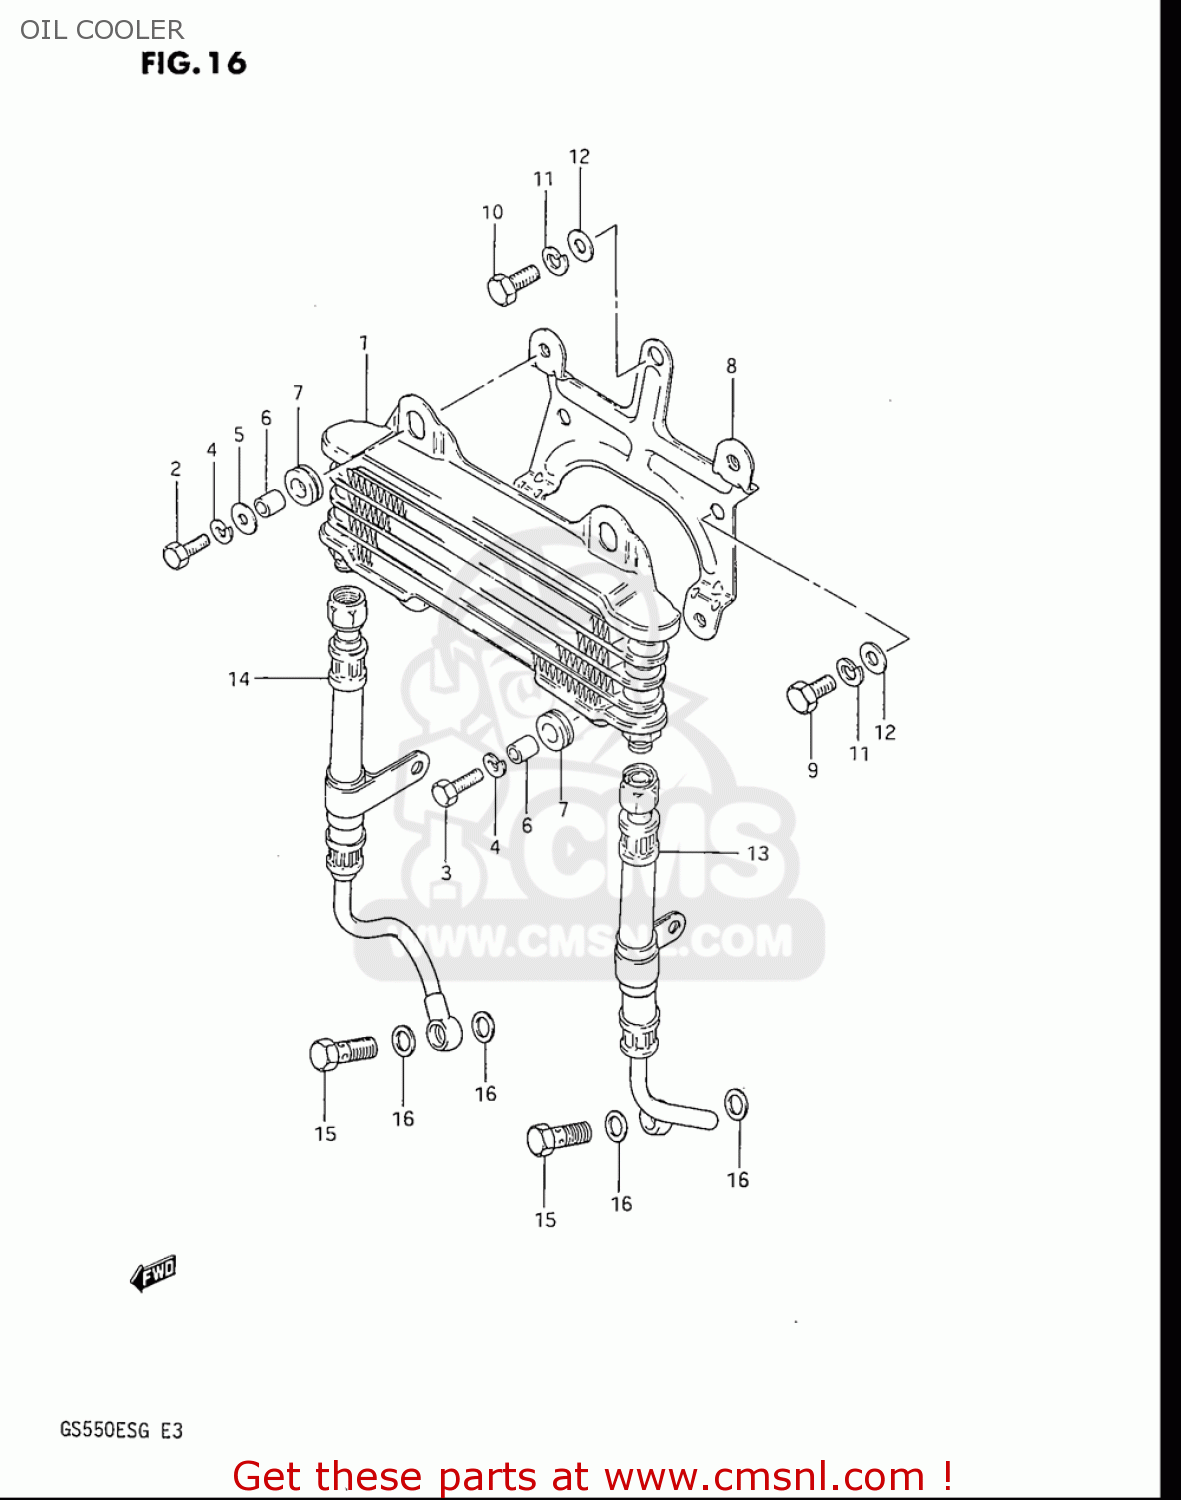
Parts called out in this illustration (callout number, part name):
2	BOLT
4	WASHER,LOCK
5	WASHER(6.5X18X1.6)
6	SPACER(6.5X10X10)
7	CUSHION
9	BOLT
10	BOLT
11	WASHER,LOCK
12	WASHER
15	BOLT UNION
16	GASKET(14X20X1.5) (NAS)
